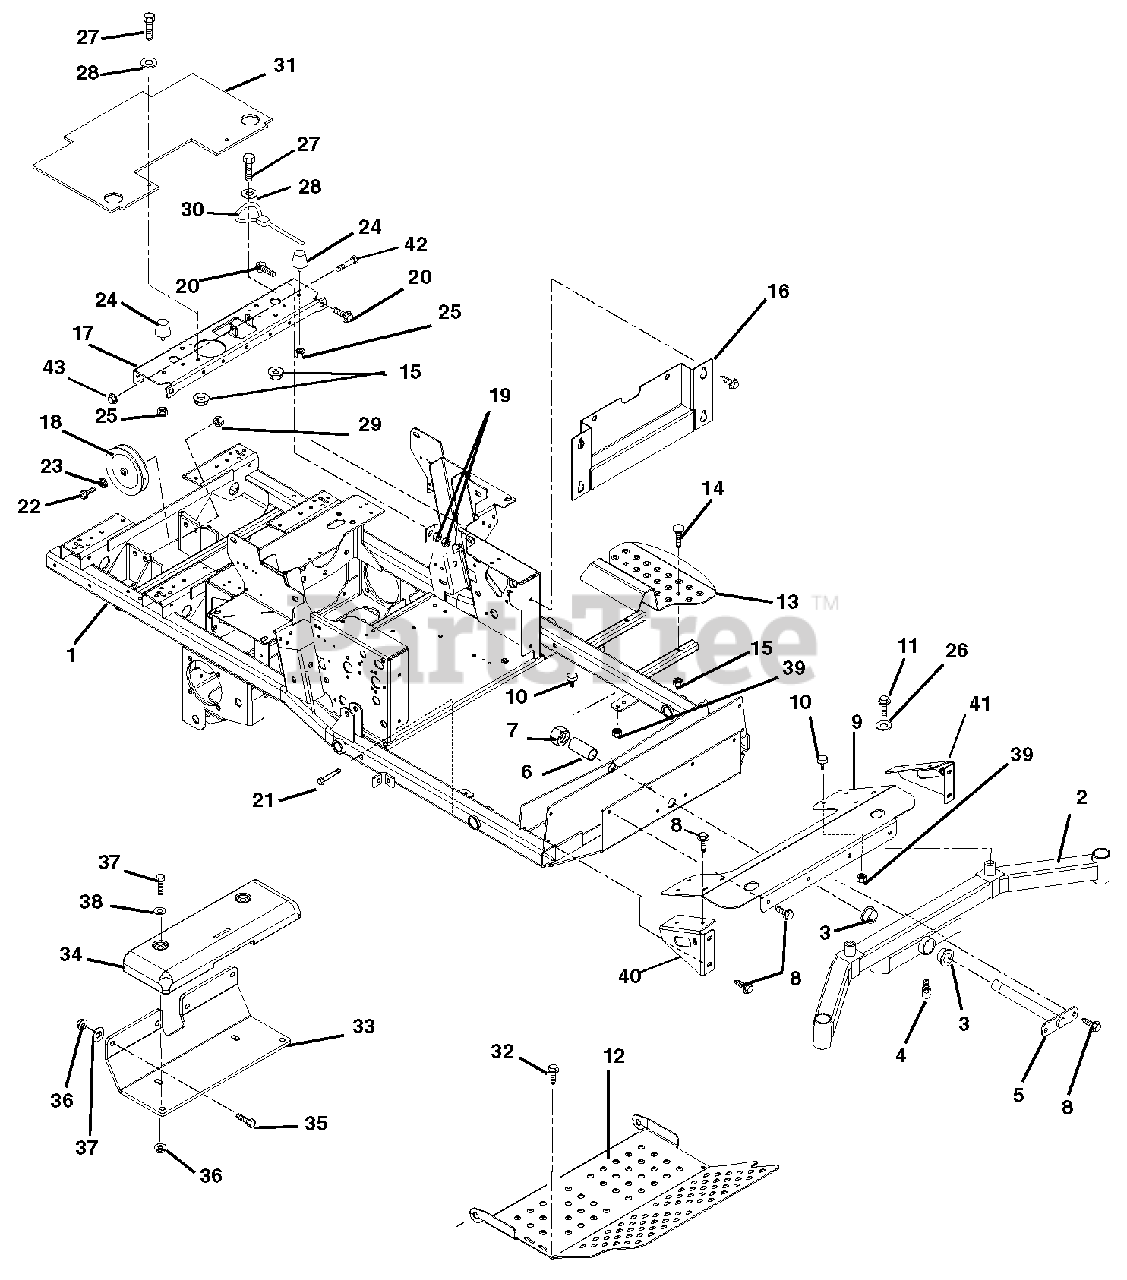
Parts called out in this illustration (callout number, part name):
1	Weldment, Frame
2	Weldment, Front Axle
3	Bushing, Flange 1.020 x 1.385 x .75 x 1.75
4	Fitting, Lube 45 Degree GM411031
5	Pin, Axle
7	Nut, Locking Nylon 1.0-14
8	Screw, Tapping .38-16 x .75
9	Axle Cover
10	Button, Bumper
11	Bolt, Hex .50-20 x 1.00 Grade 5
12	Panel, Inspection
13	Step, Ingress
14	Bolt, Round Head Square Neck .31-18 x 1.75 Grade 5
15	Nut, Locking Top Flange .31-18
16	Plate, Kick
17	Channel, Cross
18	Pulley, Idler
19	Nut, Retainer .375-16 x .37
20	Bolt, Serrated Flange Washer Head .38-16 x 1.00
21	Bolt, Hex .50-13 x 3.25 Grade 5
22	Bolt, Hex .50-13 x 2.25 Grade 5
23	Washer, Flat Steel .505 x .88 x .072
25	Nut, Spin Lock-Flange .312-18
26	Washer, Flat Steel .064 x 1.810 x .250
27	Bolt, Hex .31-18 X 1.00 Grade 5
28	Washer, Flat Steel .344 x 1.125 x .135
29	Nut, Locking Top Flange .50-13
30	Cable, Seat Prop
31	Guard, Grass
32	Screw, tapping .38-16 x 1.00
33	Bracket, Weight
34	Weight, Cast Iron
35	Bolt, Hex .50-13 x 1.00 Grade 5
36	Nut, Locking Top Flange .50-13
37	Bolt, Hex .50-13 x 4.50 Grade 5
38	Washer, Flat Steel .531 x 1.06 x .095
39	Nut, Spin Lock, Flange .312-18
40	Weldment, Right Hand Axle Cover Support
41	Weldment, Left Hand Axle Cover Support
42	Bolt, Hex .38-16X3.00 Grade 5
43	Nut, Locking-Top-Flange .38-16
